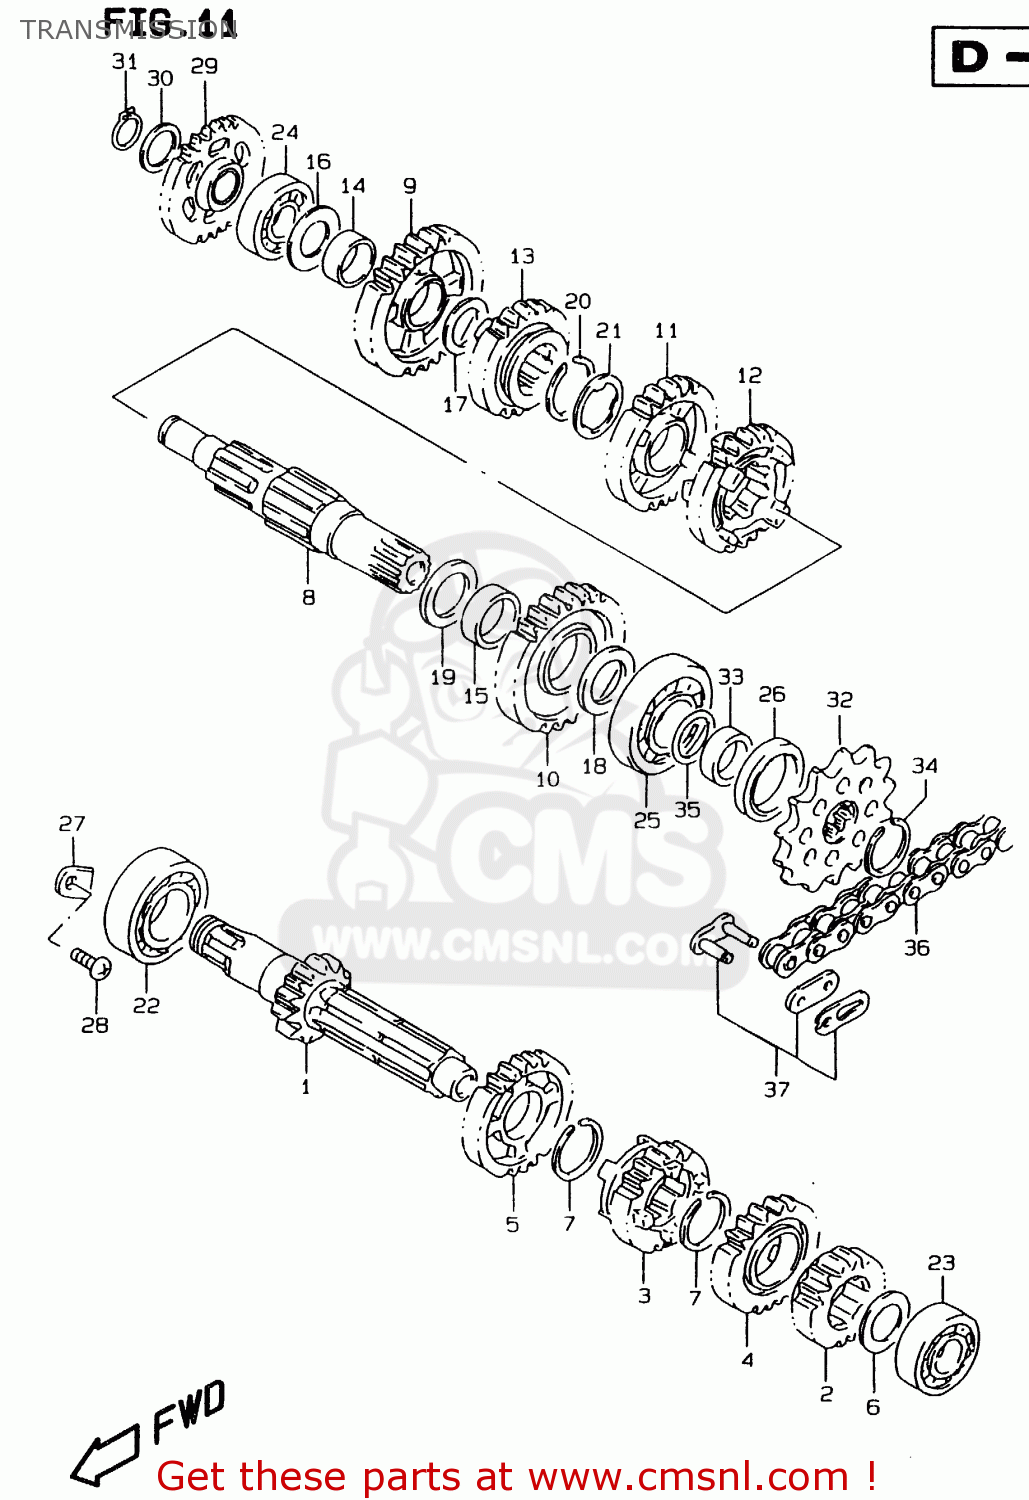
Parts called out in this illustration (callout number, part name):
1	SHAFT,COUNTER(NT:14)
2	GEAR,2ND DRIVE(NT:15)
3	GEAR,THIRD DRIVE (NT:16)
4	GEAR,FOURTH DRIVE (NT:22)
5	GEAR,5TH DRIVE(NT:22)
6	SHIM(17X30X1)
7	CIRCLIP
8	SHAFT,DRIVE
9	GEAR,1ST DRIVEN(NT:32)
10	GEAR,2ND DRIVEN(NT:26)
11	GEAR,3RD DRIVEN(NT:22)
12	GEAR,FOURTH DRIVEN (NT:24)
13	GEAR,5TH DRIVEN(NT:19)
14	BUSH(20X24X10)
15	BUSH(25X28X10)
16	SHIM(17X30X1)
17	SHIM(20X30X1)
18	SHIM (22X32X1.5)
19	SHIM(25X34X1)
20	CIRCLIP
21	WASHER,LOCK
22	BEARING(25X52X15)
23	BEARING(17X40X12)
24	BEARING(17X40X12)
25	BEARING(22X56X15)
26	SEAL,OIL(28X38X6)
27	RETAINER
28	SCREW
29	GEAR,KICK STARTER IDLE(NT:27)
30	SHIM(17X24X0.5)
31	CIRCLIP,17MM
32	SPROCKET(NT:15)
33	SPACER,ENGINE SPROCKET
34	CIRCLIP
35	O RING(D:1.9,ID:21.8)
36	CHAIN,DRIVE
37	JOINT,CHAIN
